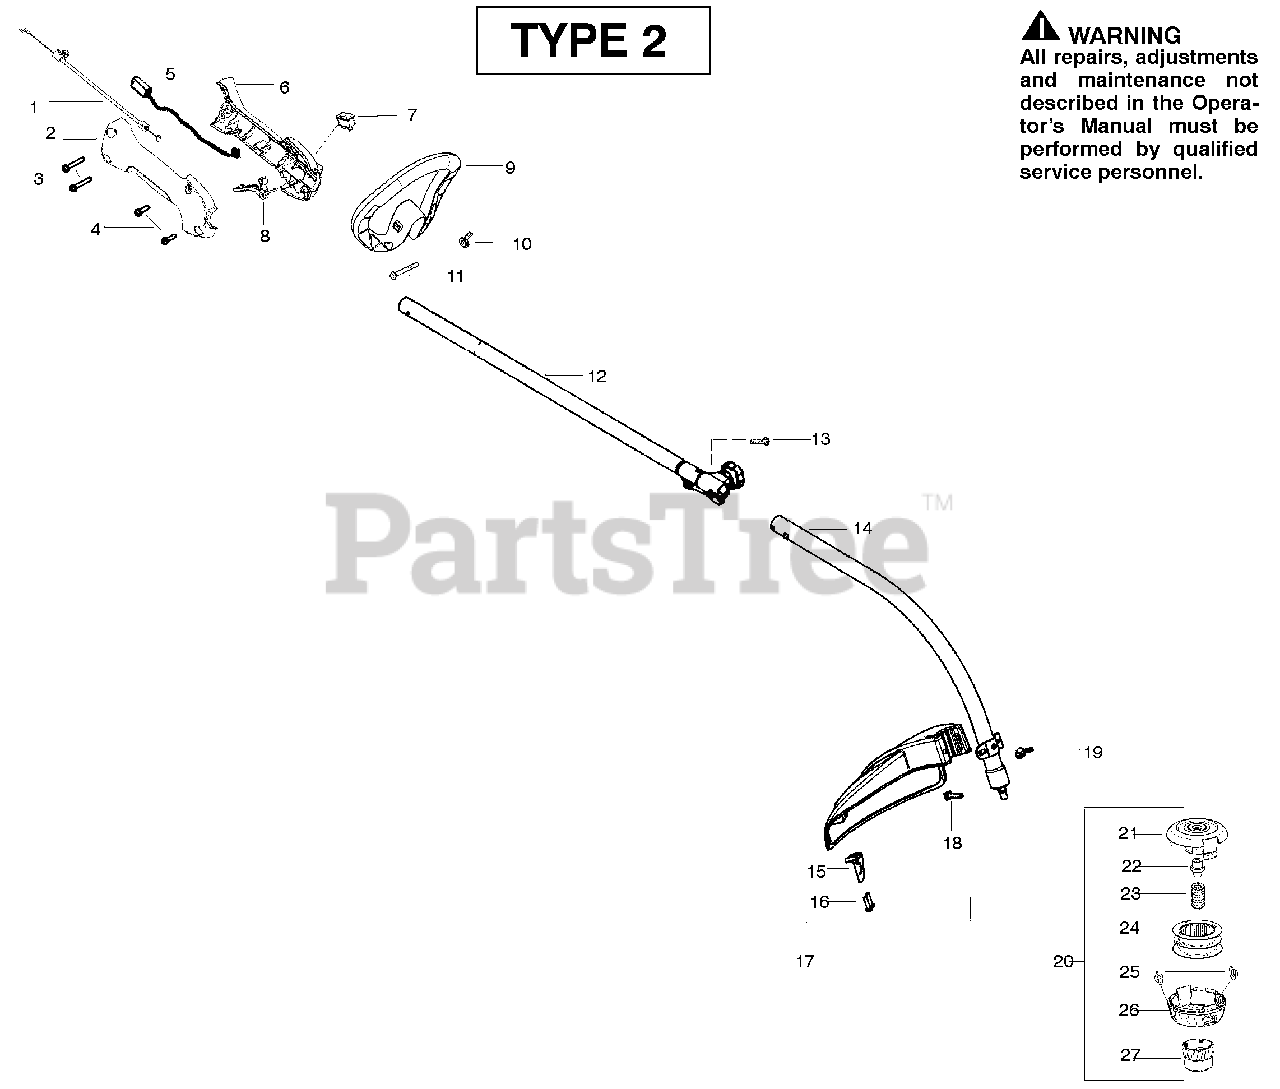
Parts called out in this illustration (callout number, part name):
2	Assy-Throttle Cable
2	Hsg.-Throttle (RH)
5	Assy.-Wire
6	Hsg. Throttle (LH)
7	Kit-Switch (momentary)
8	Trigger-Throttle
9	Handle-Assist
10	Wingnut
12	Kit-Upper Shaft
14	Kit-Lower Shaft
15	Limiter-Line
17	Kit-Shield Assy.
19	Wingnut
20	Assy-TNG7
23	Spring P25
24	Assy-Wound Spool
25	Eyelet
26	Cover
27	Knob P25
